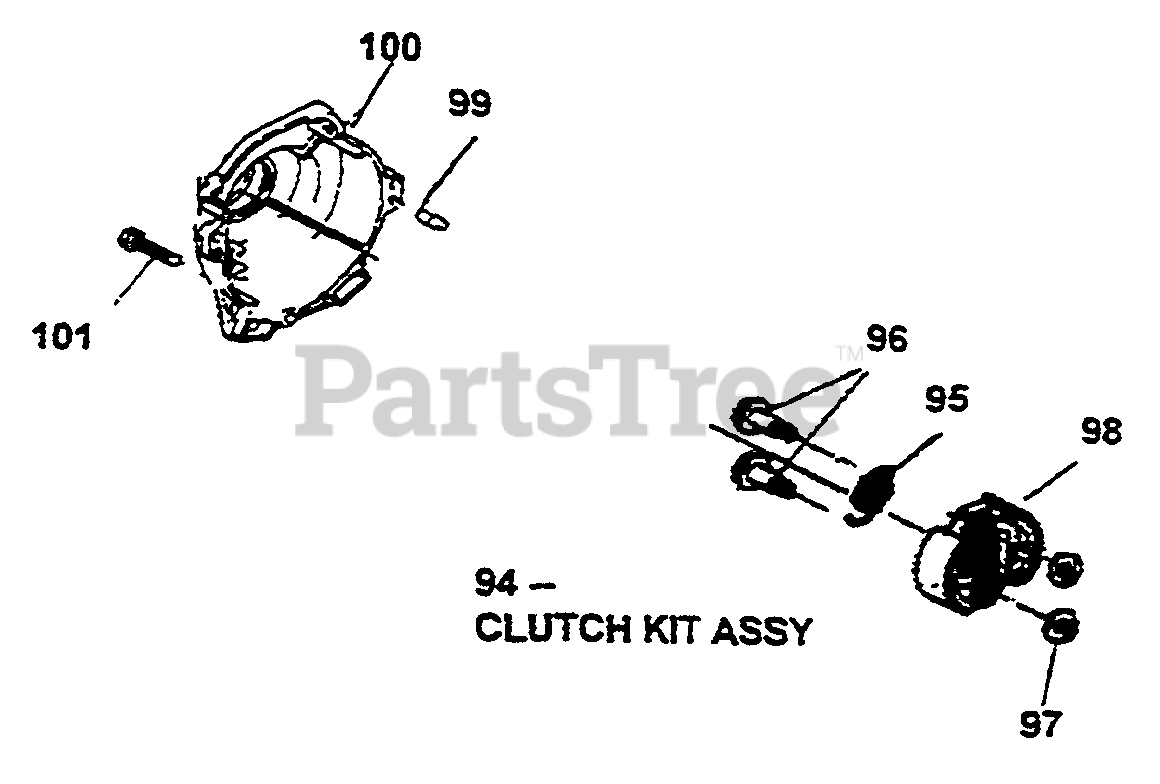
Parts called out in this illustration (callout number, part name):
94	CLUTCH SHOE ASSY
95	CLUTCH SPRING
98	CLUTCH SHOE
99	DOWEL PIN
100	CASE COVER
